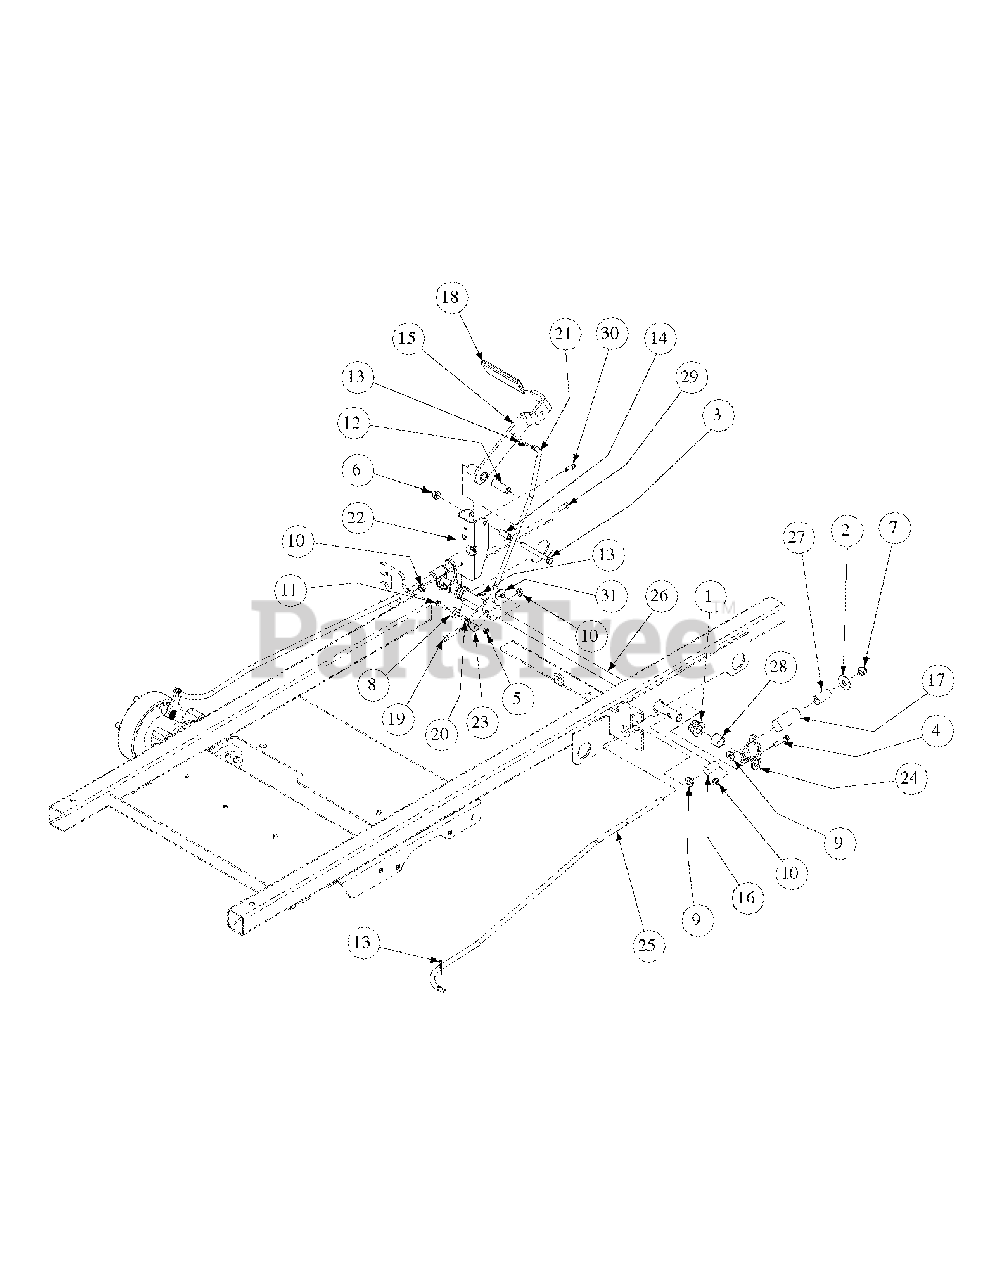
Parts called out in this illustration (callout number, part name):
1	Hex Flange Bearing, .752 ID
2	Flat Washer, 1/2
3	Hex Cap Screw, 3/8-16 x 3-1/4
4	Hex Cap Screw, 5/16-18 x 1-1/2
5	Lock Nut, 1/4-20, Nylon Insert
6	Flange Lock Hex Nut, 3/8-16
7	Nylock Nut, 7/16-14
8	Spacer, Control Rod
9	Washer, .469 ID x .875 OD x .105
10	Hex Flange Lock Nut, 5/16-18
11	Self Tapping Screw, 1/4-20 x 1.00
12	Spacer, .39 x .63 x 1.75
13	Cotter Pin, .072 x 1.12 Lg
14	Spacer, .375 x .50 x .75 Lg
15	Brake Handle
16	Neutral Brake Spring
17	Force Brake Spring
18	Parking Brake Grip
19	Socket Head Cap Screw, 5/16-18 x 1.50
20	Spacer, .375 OD x .257 ID x .438
21	Brake Rod
22	Parking Brake Mounting Bracket
23	Brake Arm Assembly
24	Brake Bracket
25	Linkage Brake Rod
26	Pivot Brake Shaft
27	Low Pressure Hose
28	Spacer, .76 ID x 1.0 OD x .75
29	HHCS, 5/16-18 x 1.0
30	Screw, TT, 1/4-20, 0.75, Hex Index Washer
31	Flat Washer, .406 ID, 1.0 OD, .105
